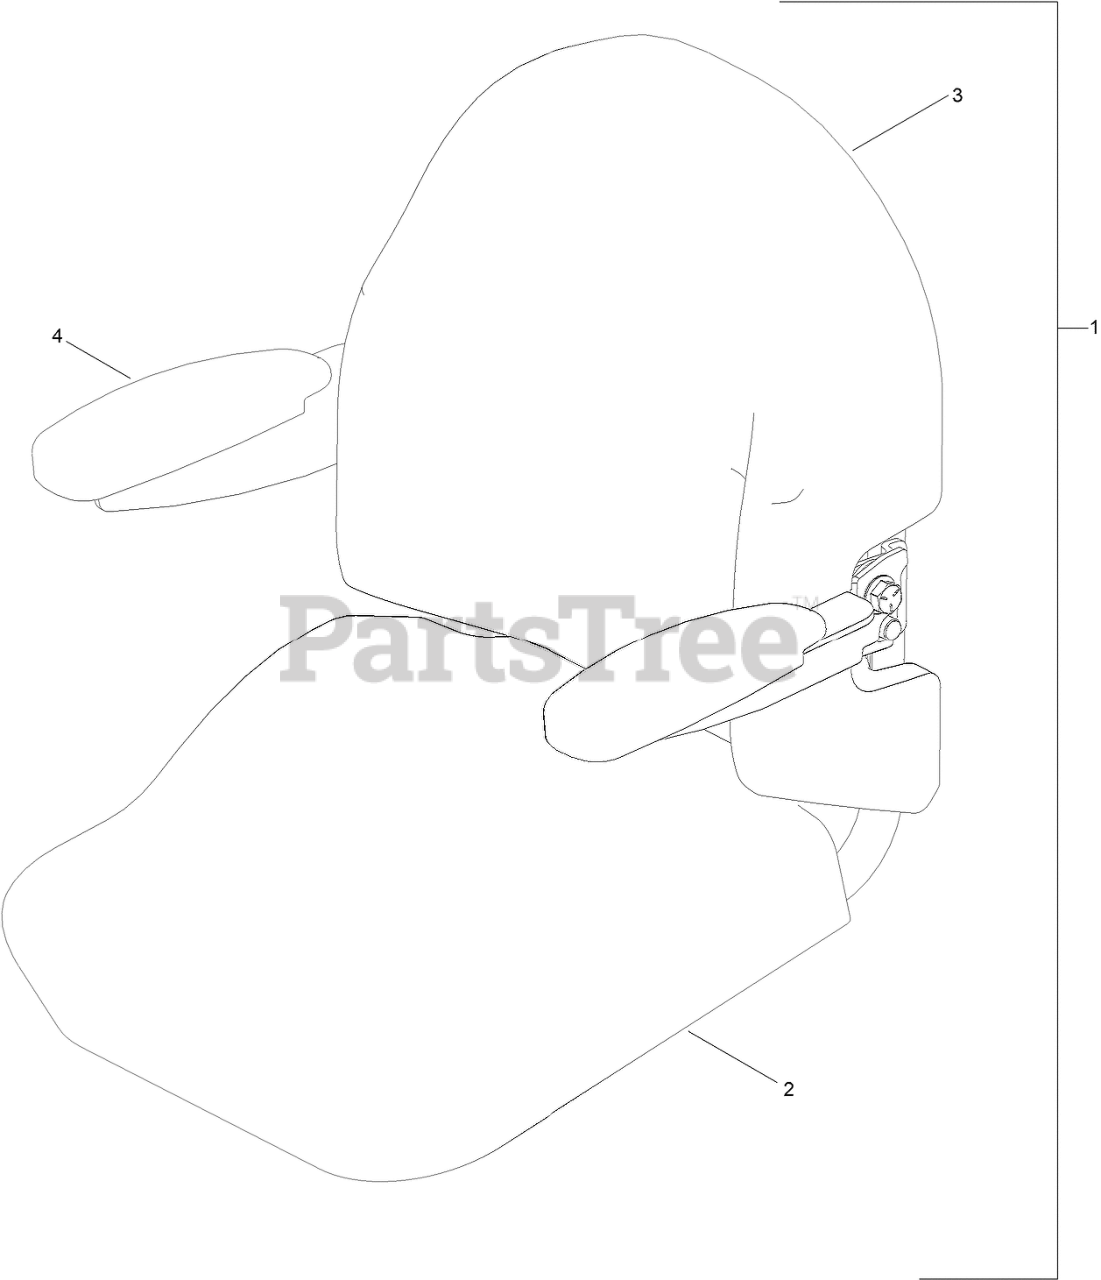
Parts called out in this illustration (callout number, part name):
1	SEAT ASM
2	COVER-BASE
3	COVER-BACK
4	KIT-ARM REST
